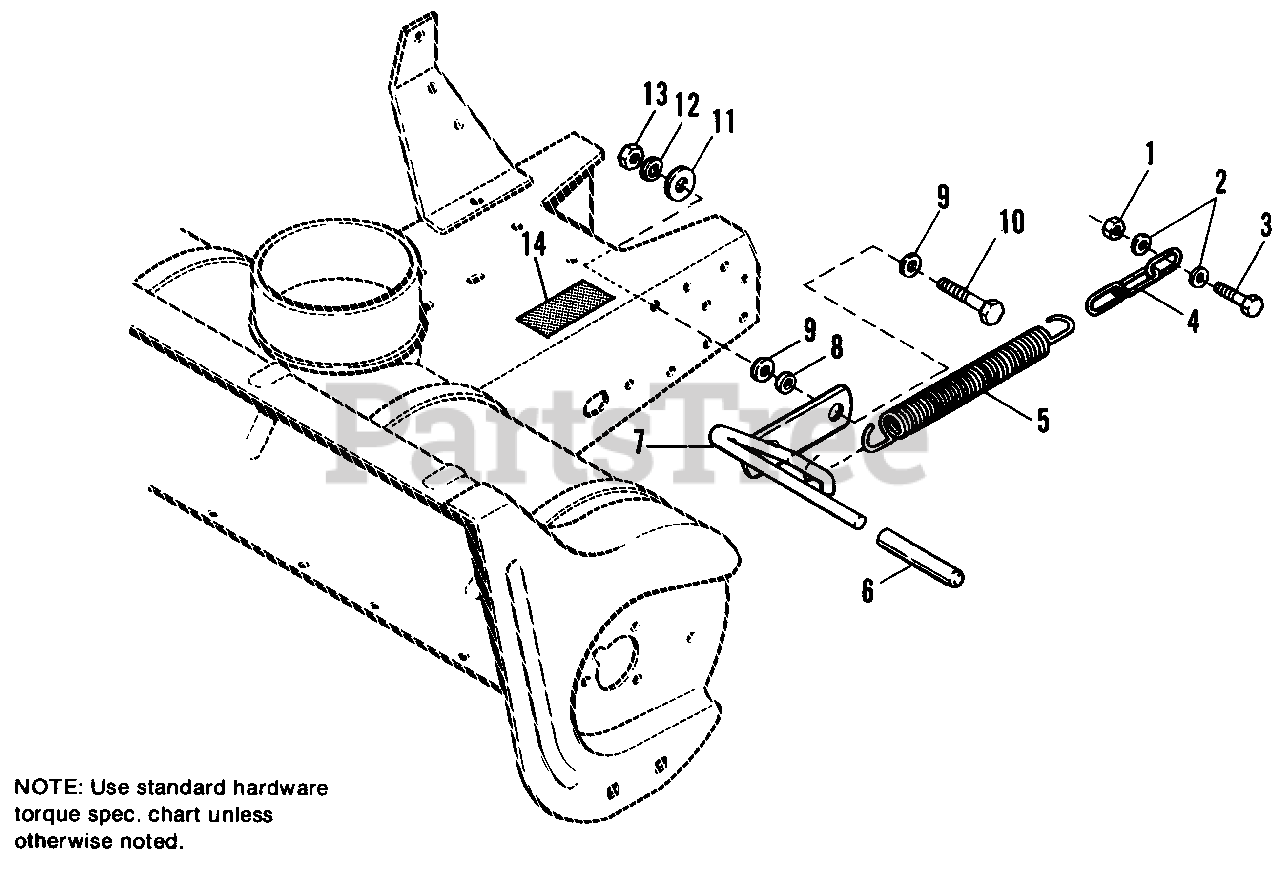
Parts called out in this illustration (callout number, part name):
1	NUT, Hex, Lock, 5/16-18
2	WASHER, Plain, 5/16
3	CAPSCREW, 5/16-18 x 1-1/4
4	CHAIN, 3-Links
7	LEVER ASSY., Spring
9	WASHER
10	CAPSCREW, 3/8-16 x 1-1/2
11	WASHER, 13/32 x 1
12	LOCKWASHER, 3/8
13	NUT, Hex, Fu11, 3/8-16
14	DECAL, Caution
